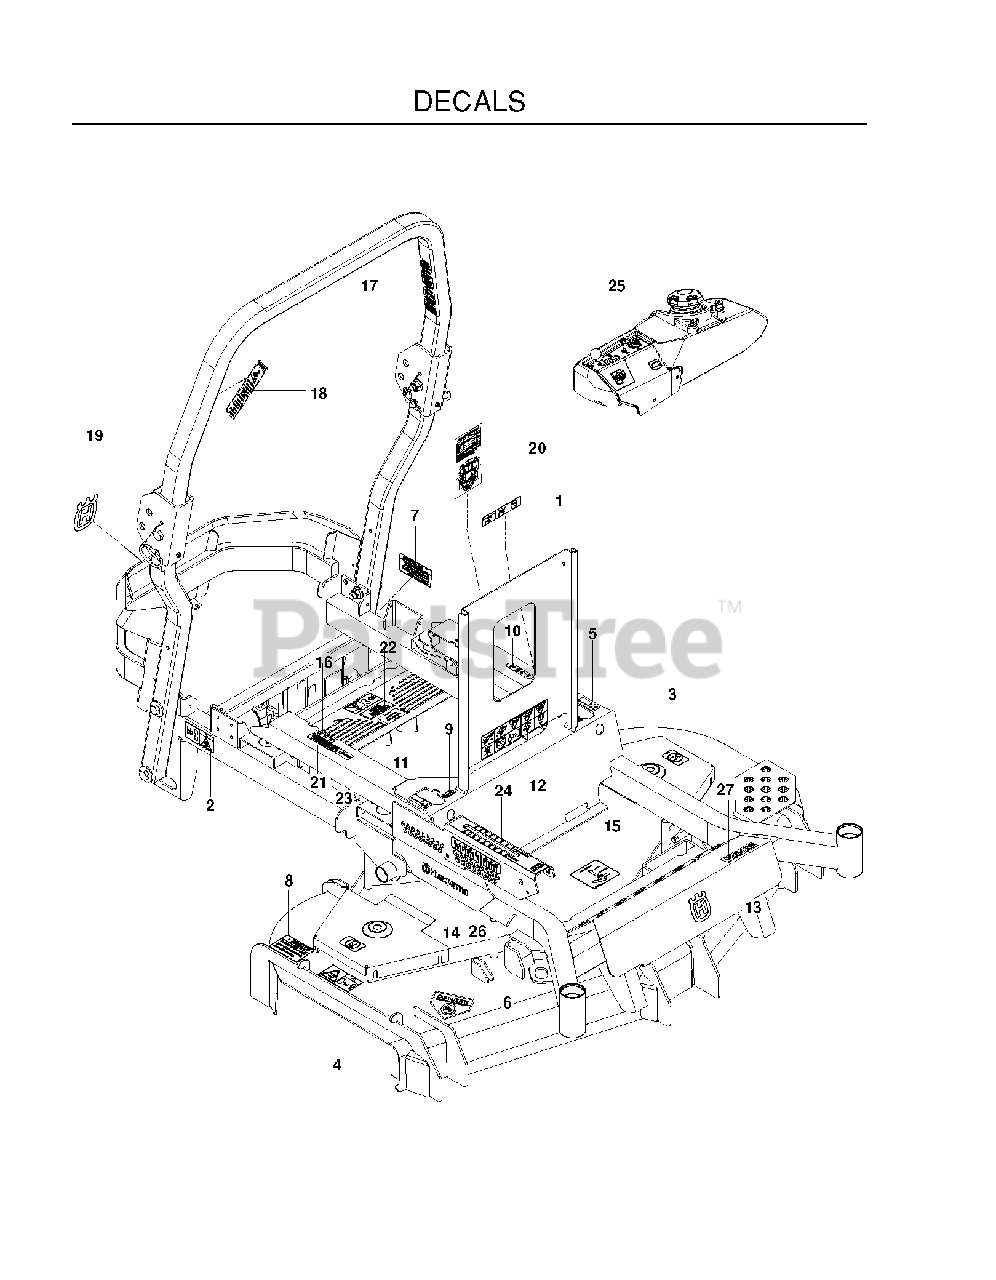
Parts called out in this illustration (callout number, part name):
1	EURO DECAL-BATTERY WARNIN6
2	DECAL, BELT DRIVE
3	DECAL, NO STEP
4	DECAL, EURO SEVERING
5	DECAL, MOTION CONTROL
6	DECAL, CPSC
7	DECAL, PROP. 65
8	DECAL, CAUTION
9	DECAL, F.S.T.
10	DECAL, PARK BRAKE
11	DECAL, OIL TANK
12	DECAL, WARNING
13	DECAL.AUGER.HUSQ.CROWN.SNOW
14	RP.DECAL.BADGE.170MM.TEXTLOGO
15	DECAL, BELT ROUTING
16	DECAL, FUSE
17	DECAL, ROPS
18	DECAL, ROPS, WARNING
19	DECAL, CROWN H, 110MM
20	DECAL, SERVICE
21	DECAL, WARNING SPARK ARRESTOR
22	HG_DECAL, ZT-5400
23	DECAL, ECM, AUSTRALIA
24	DECAL, HEIGHT
25	DECAL, CONTROL, GAS
26	DECAL, HEIGHT
27	DECAL, PZ6034ZT
